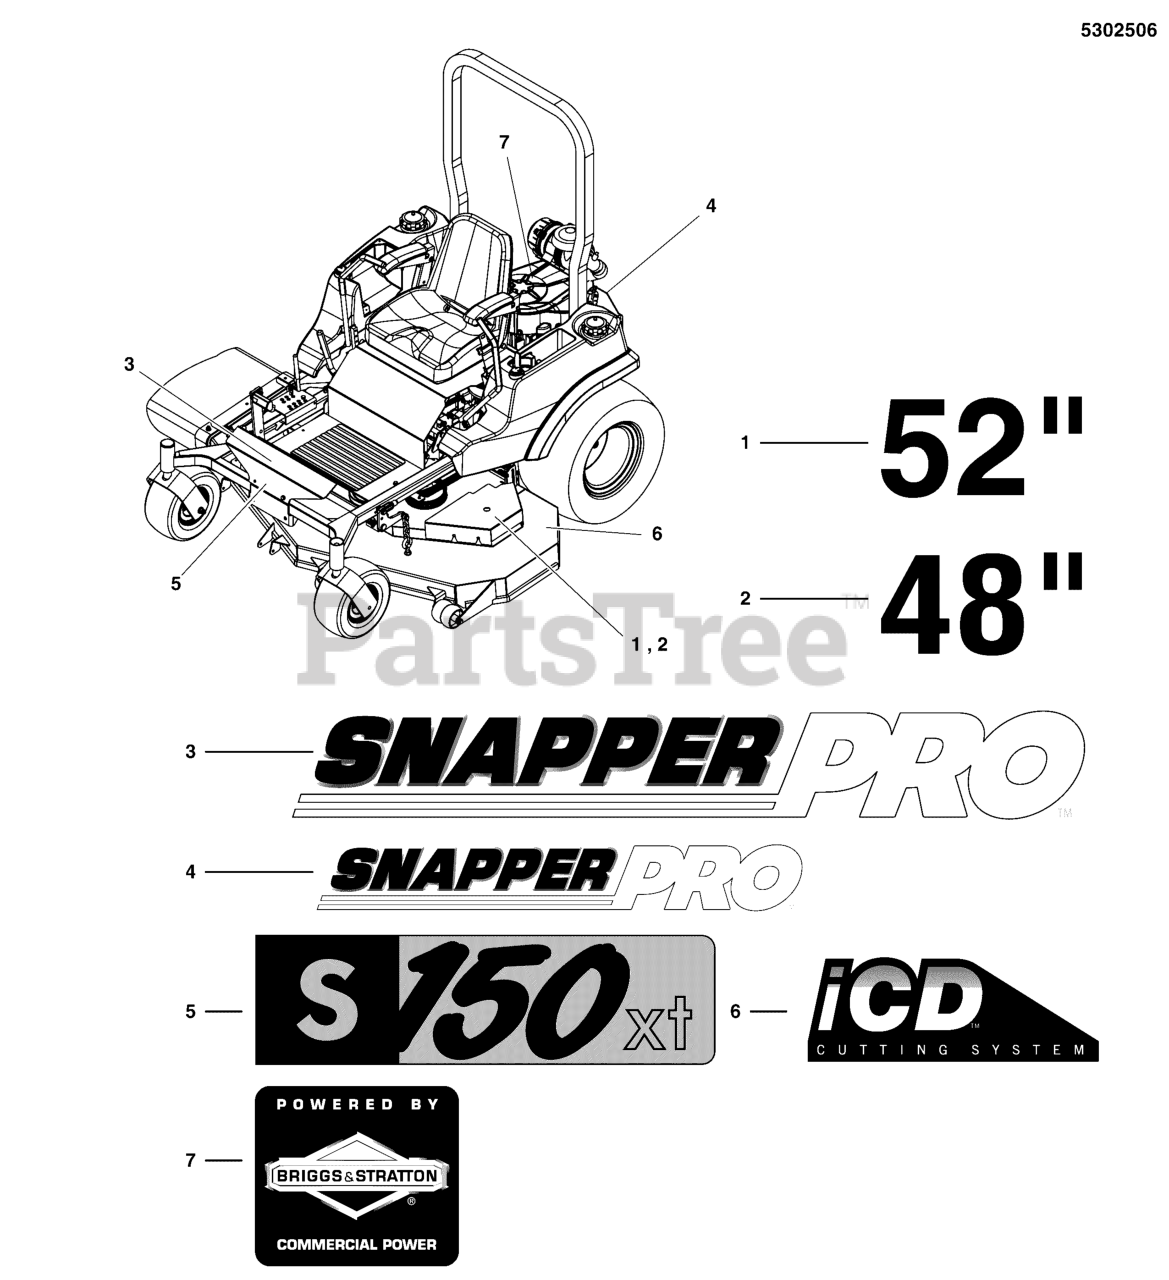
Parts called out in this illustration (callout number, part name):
1	DECAL, 52
2	DECAL, 48
3	DECAL, SNAPPER PRO, 12.87 X 1.83
4	DECAL, SNAPPER PRO, HEAT
5	DECAL, SNAPPER PRO, S150XT
6	DECAL, iCD CUTTING SYSTEM
